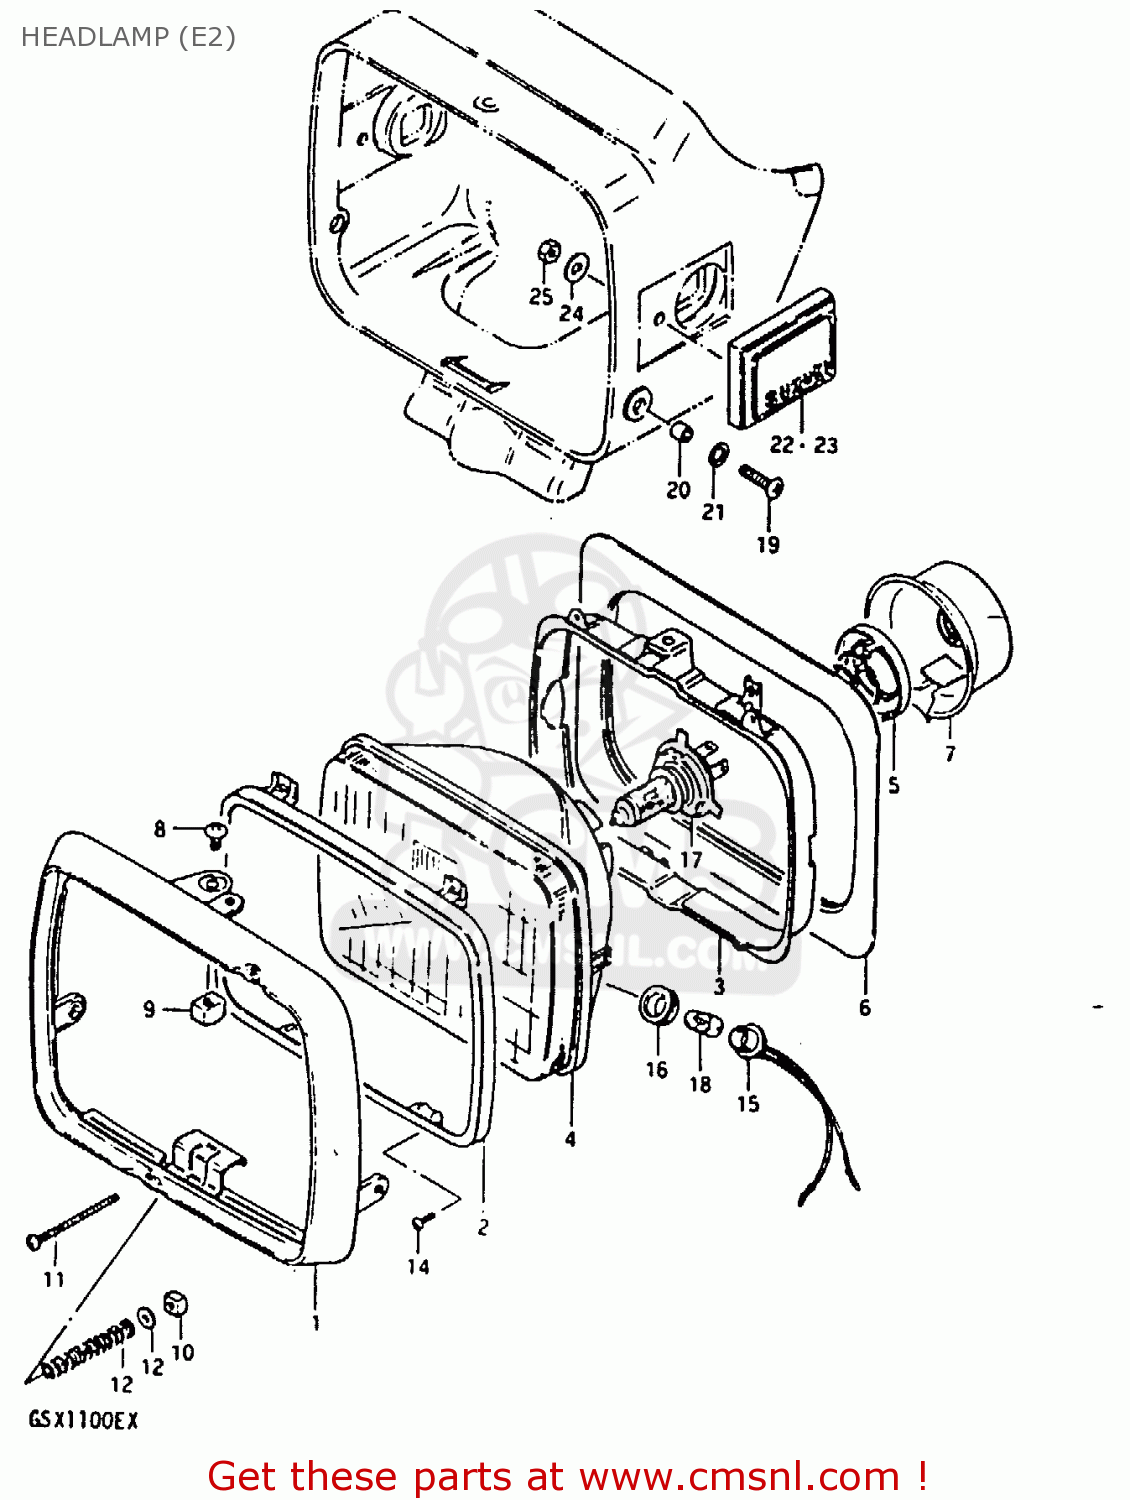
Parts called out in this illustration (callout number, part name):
1	RIM
2	RETAINER,HEADLAMP
3	RING,HEADLAMP UNIT
4	UNIT
5	HOLDER
6	SHADE
7	COVER,HEADLAMP SOCKET
8	SCREW
9	NUT,HEADLAMP ADJUSTER
10	NUT
11	SCREW,HEADLAMP ADJUST
12	WASHER
13	SPRING
14	SCREW
15	SOCKET
16	JOINT,RUBBER
17	BULB(12V60/55W,H4)
18	BULB(12V4W)
19	SCREW
20	SPACER (5.2X8X7.5)
21	GASKET(8.2X12X0.8) (NAS)
22	EMBLEM, FRONT SIDE RH
23	EMBLEM, FRONT SIDE LH
24	WASHER(5.2X16X1)
25	NUT
